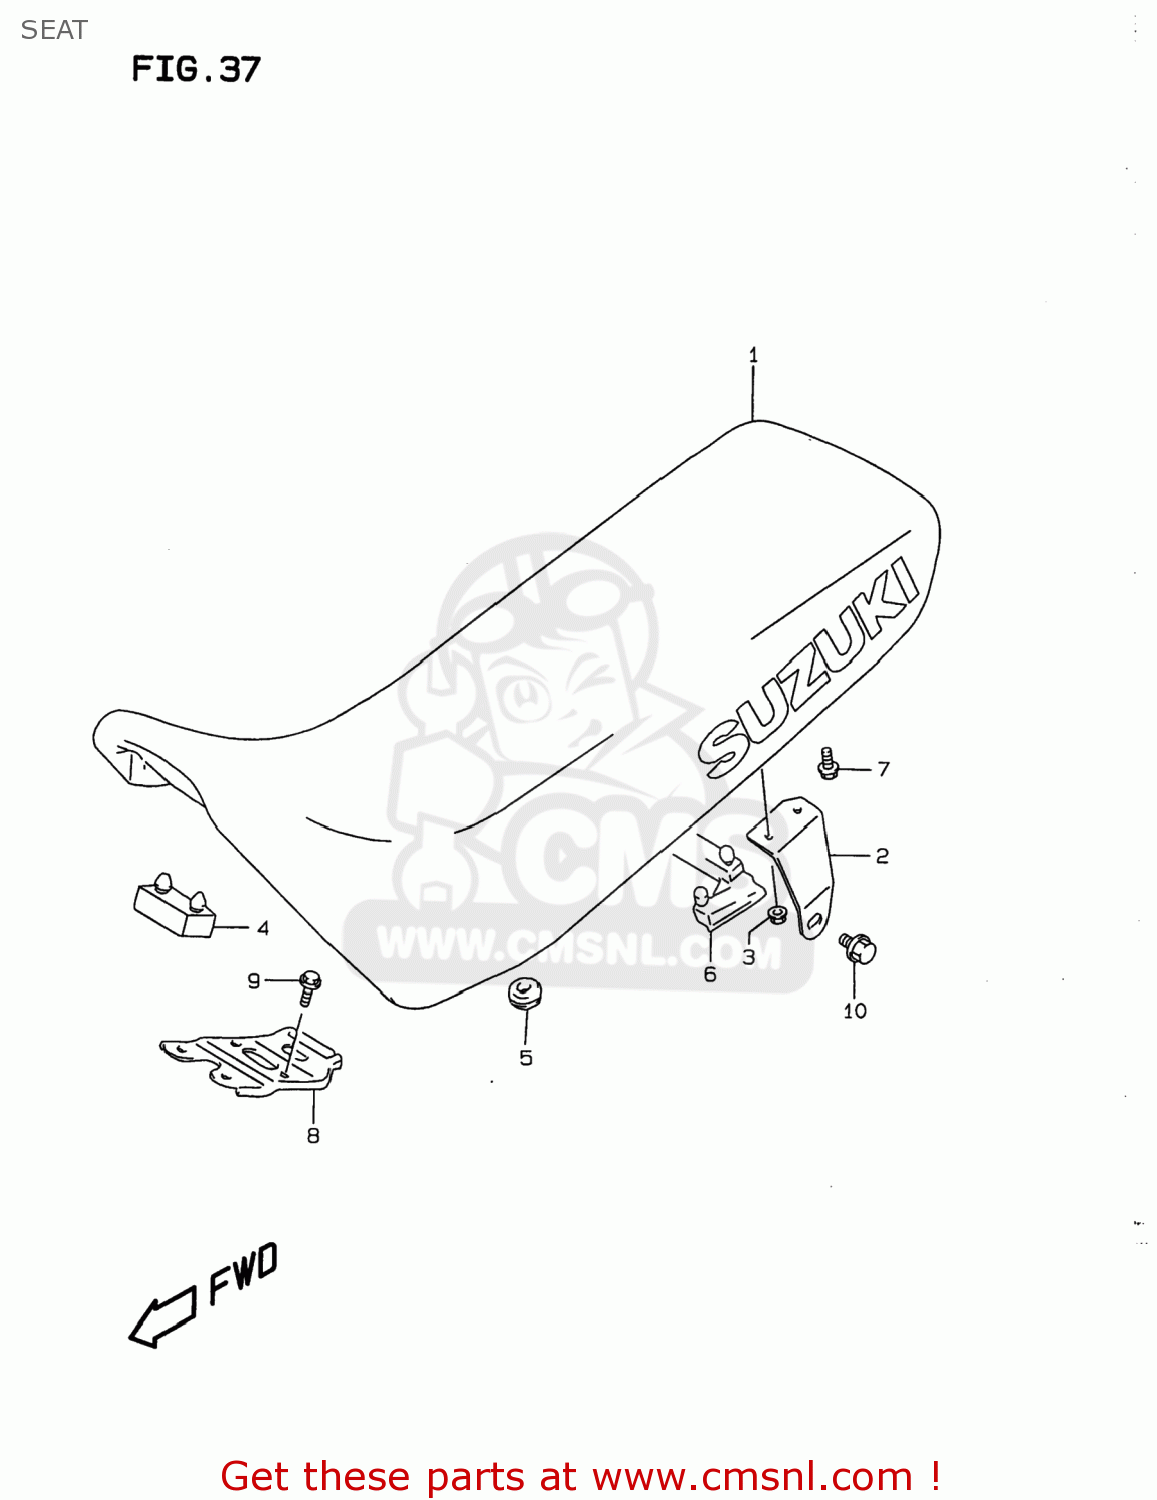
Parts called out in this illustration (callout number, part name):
1	SEAT SET
2	BRACKET,SEAT,R
3	NUT
4	CUSHION
5	CUSHION
6	CUSHION
7	BOLT
8	PLATE,SEAT FR HOOK
9	BOLT
10	BOLT
